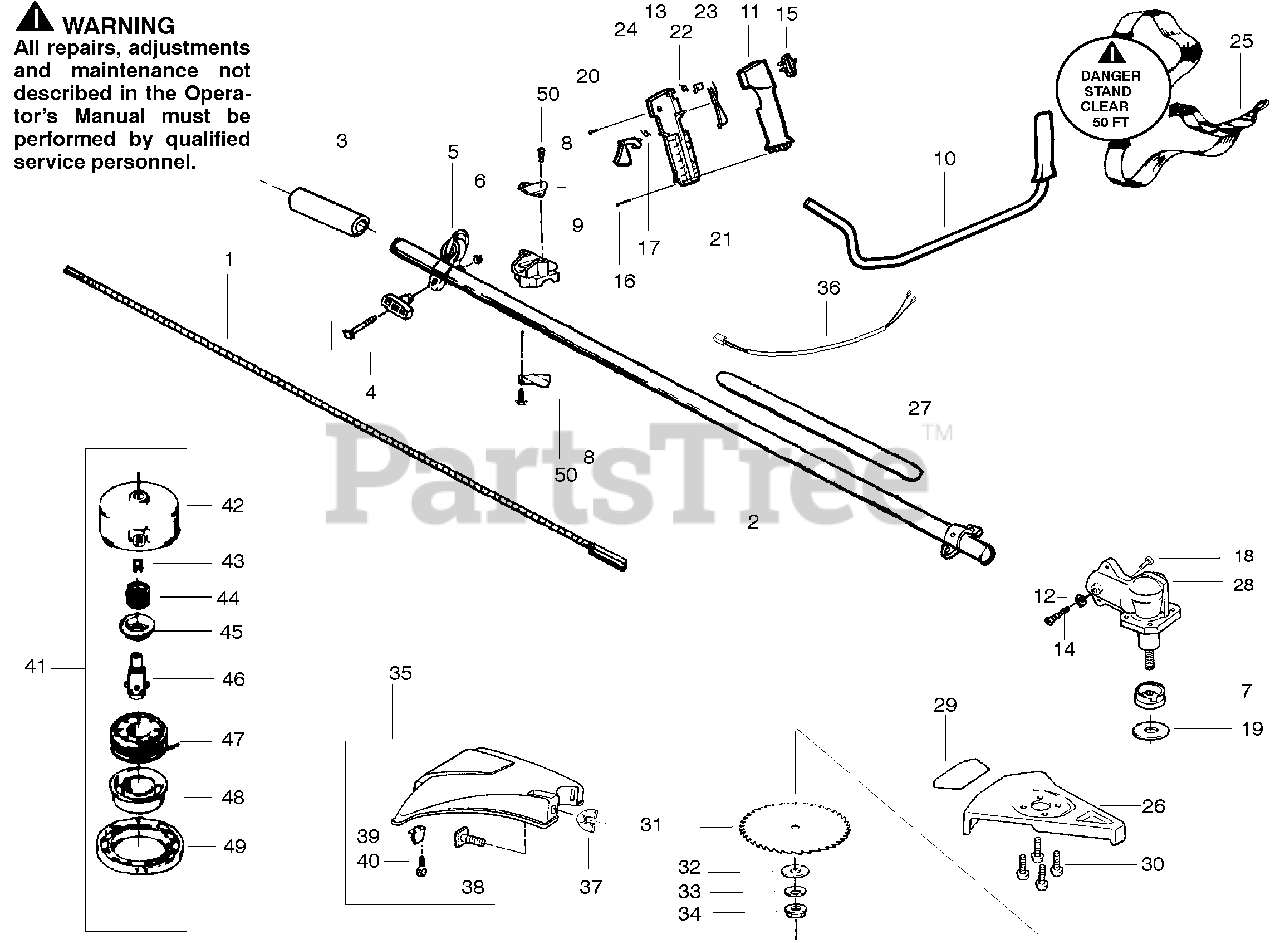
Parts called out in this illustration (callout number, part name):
1	Flex-Shaft-57"
2	Drive Shaft Housing
3	Pad-Drive Shaft
4	"T" Handle Ass'y.
5	Clamp Harness Assy.
7	Dust Cup
8	Handlebar Bracket
9	Clamp-Handlebar
10	Handlebar Ass'y.
11	Throttle Hsg. Left
12	Lockwasher-Locator
13	Throttle Hsg. Right
14	Screw-Locator
15	Rocker Switch
17	Trigger Spring
18	Screw-Pinch Clamp
19	Washer-Blade Ret.
21	Throttle Lockout
22	Spring Throttle Lock
23	Throttle Lock
24	Throttle Trigger
25	Shoulder Strap
26	Blade Shield Kit
27	Shaft Warning Decal
28	Gear Box Ass'y.
29	Decal Blade Direction
31	Brush Blade
32	Washer-Flat
33	Washer-Spring Bevel
34	Nut-Flange
35	Shield Kit Ass'y.
36	Wire Harness Ass'y.
37	Wingnut
39	Line Limiter
40	Screw
41	Cutting Head Ass'y.
42	Hub Ass'y.
43	Line Saver
45	Cap Spring
46	Drive Gear
47	Accy-Spool w/line
48	Release Button
